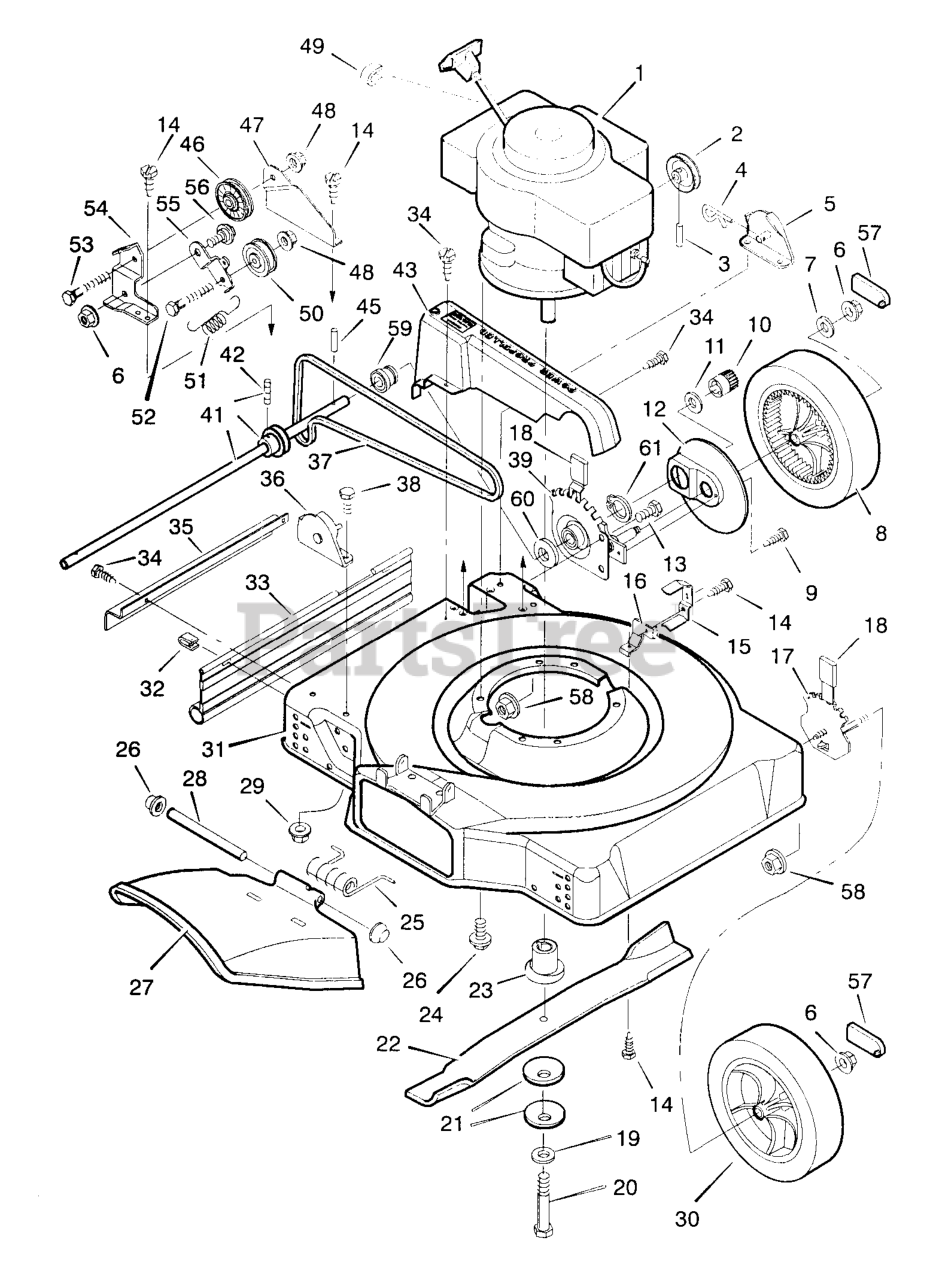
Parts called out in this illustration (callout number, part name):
1	Engine *
3	Pin, Spring
4	Pin, Hair
5	Bracket, Left Handle
6	Nut
7	Washer
8	Wheel, Drive
10	Gear, Right Pinion
12	Cover, Dust
13	Bolt, Hex
15	Guide, Belt
16	Belt Guide, Briggs
17	Height Adjuster, Front
21	Washer, Belleville
23	Adapter, Blade
24	Bolt, Engine
25	Spring, Torsion
26	Push On Cap
27	Deflector, Chute
29	Nut
30	Wheel and Tire, Front
31	Housing
32	Retainer
33	Deflector, Rear
35	Guard, Axle
36	Bracket, Right Handle
37	Belt, Briggs & Stratton
39	Height Adjuster, Left
41	Axle, Pulley & Setscrew
42	Setscrew
43	Belt Guard, Briggs
45	Pin, Drive
46	Pulley, Idler
47	Support, Idler
48	Nut
49	Stop, Rope
50	Pulley, Idler
51	Spring, Extension
52	Bolt, Hex
53	Bolt, Hex
54	Bracket, Idler
55	Arm, Idler
56	Bolt, Shoulder
57	Cap, Hub
58	Nut, Flange
59	Bearing and Retainer
60	Washer, Belleville
61	Retainer Ring
